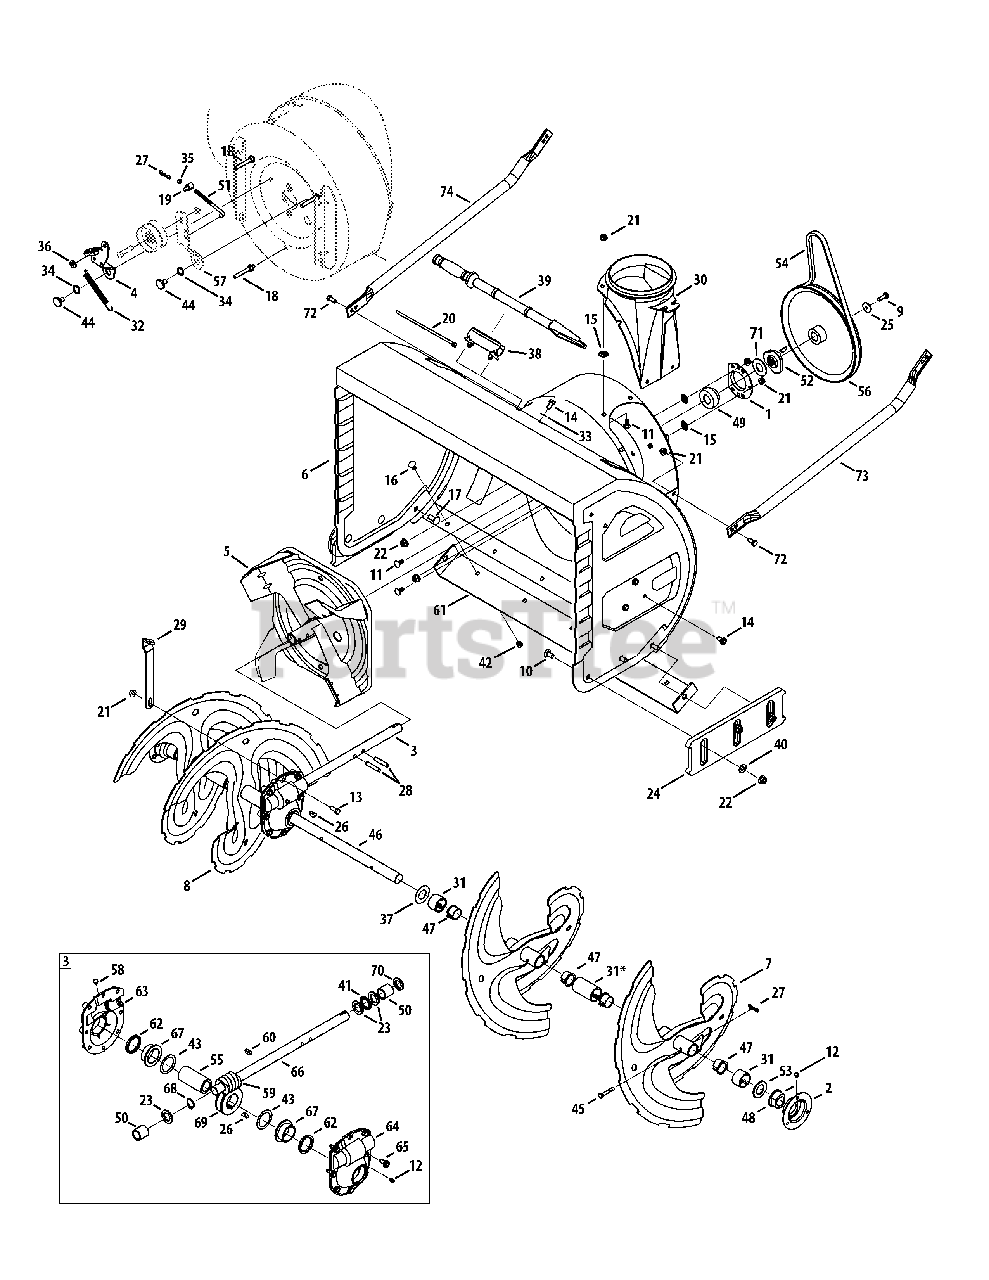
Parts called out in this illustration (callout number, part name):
1	Housing, Bearing
3	Gear Box Assembly
4	Bracket Assembly, Auger Brake
5	Impeller, 16"
6	Housing, Auger - 30"
6	Housing, Auger - 33"
7	Spiral Assembly, LH
8	Spiral Assembly, RH
9	Screw, Hex Cap Lock, 5/16-24
10	Screw, Carriage, 3/8-16 x 1.00
11	Screw, Carriage, 5/16-18 x .75
12	Fitting, Lube
13	Screw, Hex Cap, 5/16-18 x 1.0 Gr5
14	Screw, 5/16-18 x .750
15	Nut, Push
16	Screw, Carriage, 5/16-18 x .75
17	Screw, Carriage, 3/8-16 x 1.25
18	Screw w/Stud, 5/16-18 x .4300
20	Tie Strap
21	Nut, Hex Flange Lock, 5/16-18
22	Nut, Hex Flange Lock, 3/8-16
23	Wash, Flat, .88 ID x .38 OD
24	Shoe, Skid, Deluxe
25	Washer, Flat, .34 x 1.5 x .15 Ht.
26	Key, Woodruff, 1/4 x 3/4
27	Pin, Bow-tie Cotter
28	Pin, Spiral, 5/16 x 1.75
29	Bracket, Gear Box Support
30	Adapter, Chute, 6"
31	Spacer, 1.0 x 1.5 x 1.0 Lg - 30" ONLY
31	Spacer, 1.0 x 1.5 x 2.5 Lg - 33" ONLY
32	Spring, Extension
33	Washer, Flat, .349 x .879 .063
34	Washer, Wave, .625 x .885 x .015
35	Jam Nut, 5/16-18
36	Washer, .344 x .75 x .12
37	Washer, 1.01 x 1.86 x .06
38	Clip, Mounting
39	Tool, Clean-out
40	Wash, Flat, .385 x .870 x .092
41	Bearing, Thrust
42	Nut, Hex, 5/16-18 Stainless
43	Wash, Flat, 1.52ID x 2.0 OD
44	Screw, Shoulder, .625 x .17
45	Pin, Shear, .25 x 1.75
46	Shaft, Spiral, 30" ONLY
46	Shaft, Spiral, 33" ONLY
47	Bushing, Flange,
48	Bearing, Flange w/Flats
49	Bearing, Self Aligning
51	Rod, Auger Idler
52	Adapter, Pulley w/Pins
53	Spacer, 1.004 x 1.375 x .25
54	V-Belt, 1/2 x 42
55	Shaft, Gear, Worm
56	Pulley, Auger Drive, 10.0
57	Bracket, Auger Idler
59	Gear, Worm
60	Key, Hi Pro, 3/16 x 3/4
61	Plate, Shave 30"
61	Plate, Shave 33"
63	Hsg, Ass’y, Auger RH (Incl. Ref. 62 & 67)
64	Hsg, Ass’y, Auger LH (Incl. Ref. 62 & 67)
65	Screw, LD, 5/16-18 x .750
66	Shaft, Drive, Auger
67	Flange Bearing
68	External, Retaining, Ring
69	Gear, Worm, LH
70	Seal, Oil
71	Washer, Flat, .76 x 1.49 x .06
72	Hex Cap Screw, 5/16-18 x .75
73	Support Tube, LH
74	Support Tube, RH
